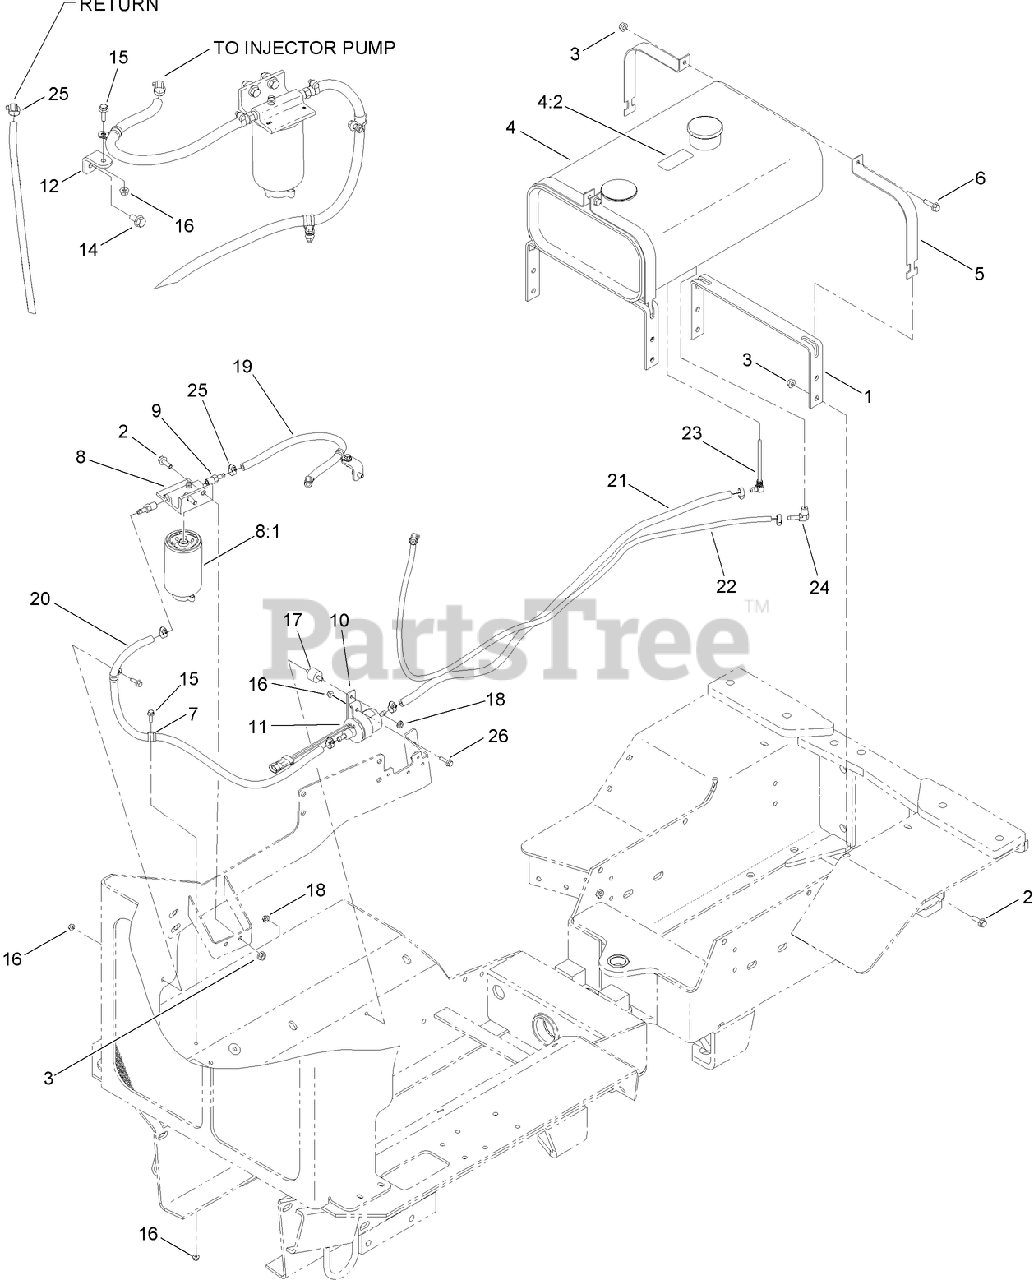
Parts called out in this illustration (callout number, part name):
1	BRACKET-TANK, FUEL
2	SCREW-HHF
3	NUT-HF
4	TANK-FUEL W/DECAL
4:2	DECAL-LOW SULFUR
5	STRAP-TANK, FUEL
6	SCREW-HHF
7	CLAMP-R
8	SEPARATOR-FILTER
8:1	FILTER-SPIN ON
9	FITTING-STRAIGHT
10	BRACKET-PUMP, FUEL
11	PUMP-FUEL
14	SCREW-HHF
15	SCREW-HHF
16	NUT-HF
17	MOUNT-ISOLATER
18	NUT-HF
19	HOSE-FUEL
20	HOSE-FUEL
21	HOSE-FUEL
22	HOSE-FUEL
23	FITTING
24	STEM-90 (BARB HOSE)
25	CLAMP-WORM
26	SCREW-HHF
